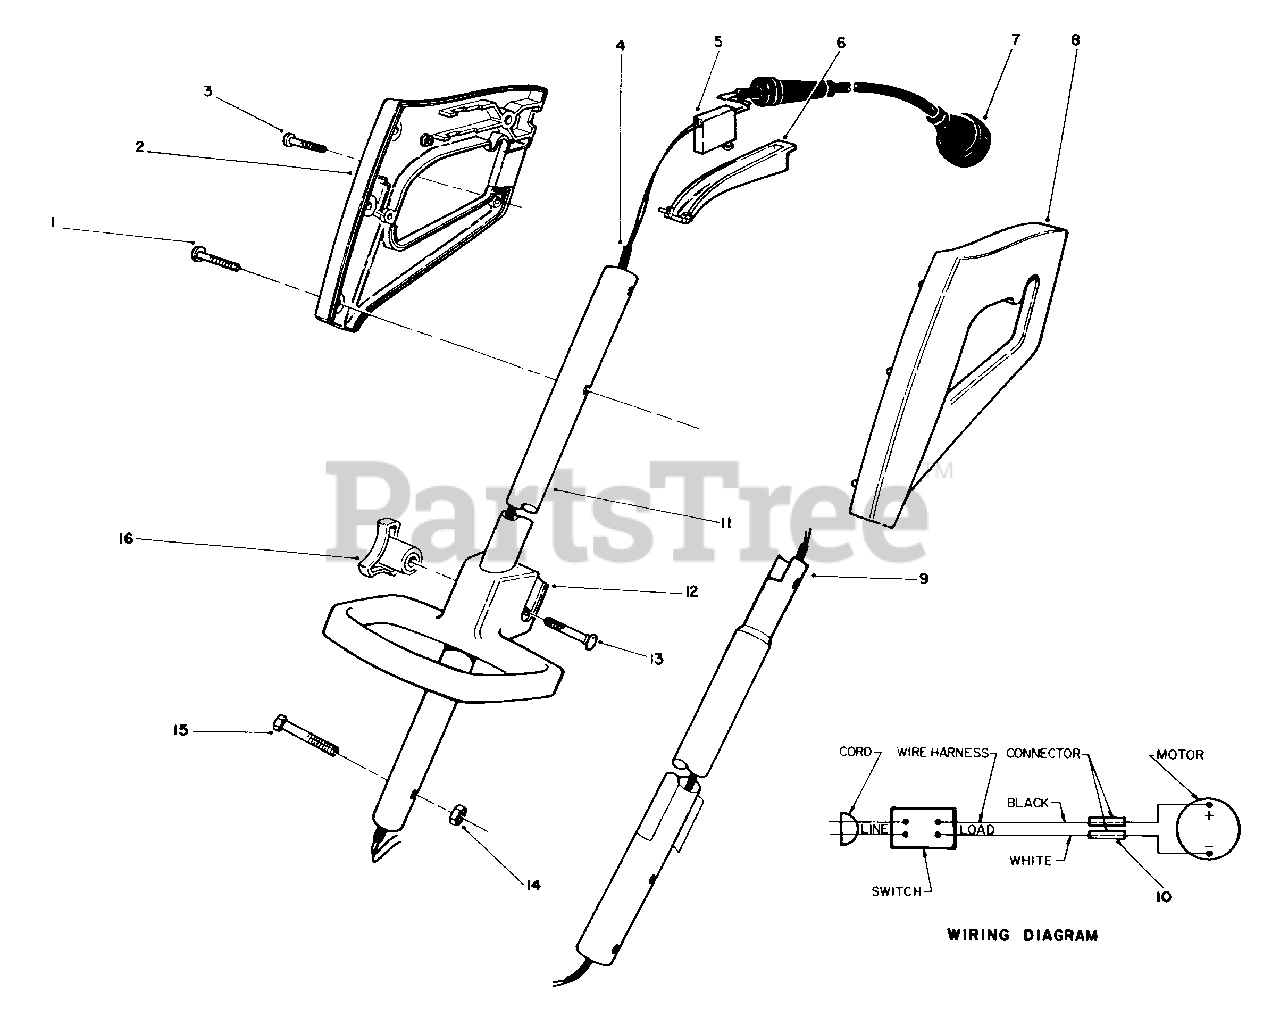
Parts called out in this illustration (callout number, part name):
1	Screw-Hex. Hd. Cap
2	Grip-Handle R.H.
3	Screw-Pan Hd.
4	Wire Harness Assembly
5	Switch
6	Bar-Switch
7	Cord-Power
8	Grip-Handle L.H.
9	Tube-Lower
10	Connector
11	Tube-Upper
12	Handle-Adjustable
13	Bolt-Carriage
14	Nut-Lock
15	Screw-Hex. Hd. Cap
16	Knob-Adjustment Handle
